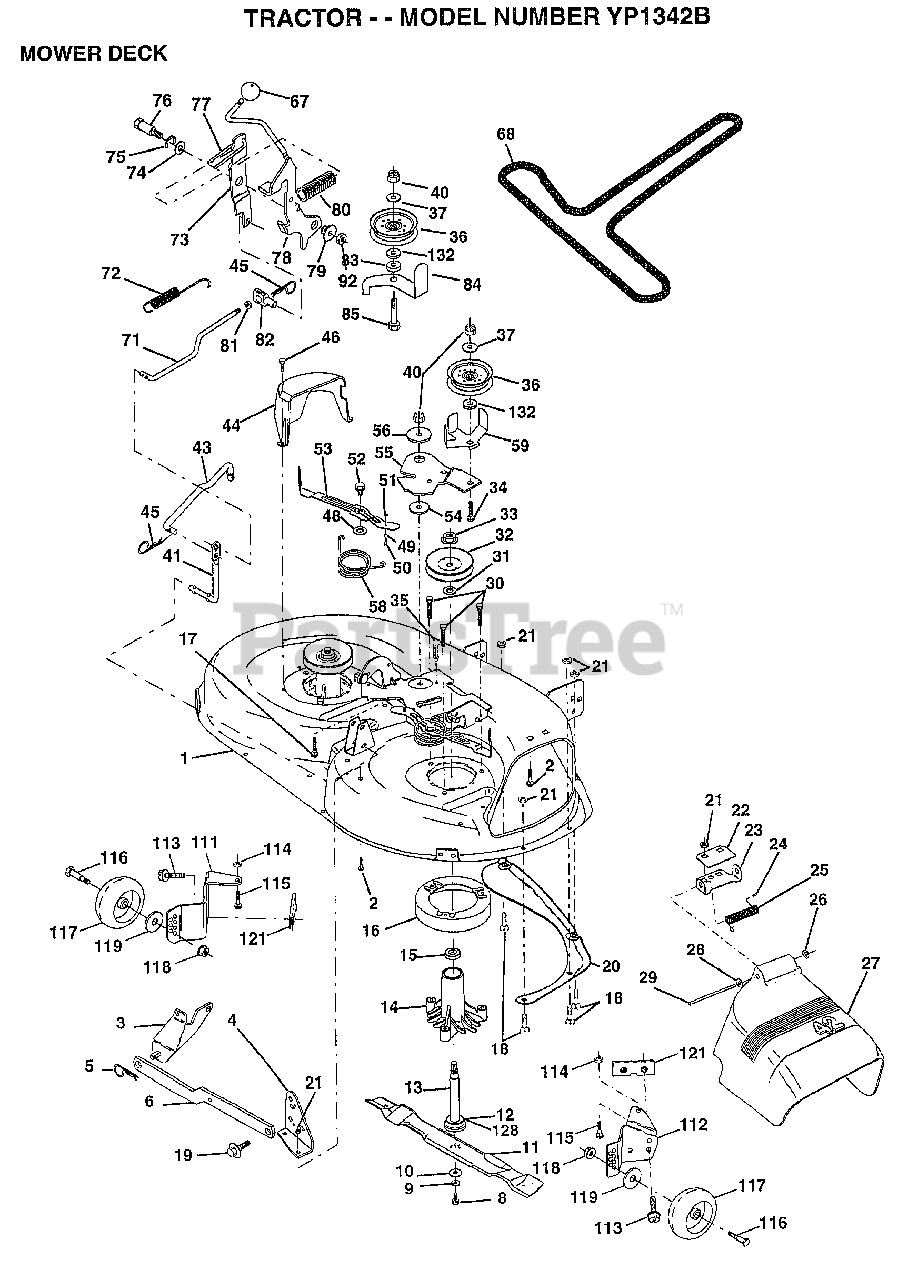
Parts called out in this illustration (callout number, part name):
1	DECK.WELD.42.
2	BOLT
3	BRKT ASM SWAY BAR
4	BRKT DECK SW BAR
8	BLADE BOLT
10	WASHER.HARD.BLADE
11	"BLADE.42"" HIPERF"
12	BEARING.BALL
14	HSG ASM MANDREL
15	BEARING
16	STRIPPER RND MWR
17	BOLT RDHD 3/8-16
18	BOLT
19	BOLT SHD 5/16-18
22	STIFFENER BRKT
23	DEFLECTOR BRKT
24	CAP-SLEEVE LT
25	SPRING TORSION
26	NUT PUSH M
27	DEFLECTOR.SHIELD
28	WASHER
29	HINGE ROD
30	"SCREW-THD ROLL,WA"
31	WASHER
32	PULLEY.MANDREL.42
34	BOLT
35	XMAS TREE FASTNER
36	FLAT IDLER PULLEY
37	WASHER
41	PIVOT ROD
43	ROD CLUTCH W/NIBS
44	GUARD MAND LH BLK
45	RETAINER M
46	SCREW.1/4-20X5/8
48	HARD SMALL WASHER
49	ROLLER ASM-CAM
50	SHOULDER BOLT
51	LOCKNUT
52	BOLT.SHLD.5/16-18
54	HARDENED WASHER
55	ARM-IDLER
56	SPACER RETAINER
58	SPRING TORSN BRAK
59	GUARD IDLER TUV
67	KNOB T(3/8 HOLE)
68	BELT.V.T-PATH
71	ROD CLUTCH 38/42
72	RETURN SPRING
73	CLUTCH ARM SECOND
74	WASHER
75	RING
76	SHOULDER BOLT
77	SPRING KEEPER
78	LEVER ASM-CLUTCH
79	BUSHING
80	SPRING.CLUTCH.MWR
81	TRUNION ADJ
82	NUT
83	WASHER
84	"KEEPER-BELT,FIXED"
85	BOLT RDHD 3/8-16
92	NUT
111	BRACKET.GWHL.LH.
112	BRACKET.GWHL.RH.
113	SCREW
116	BOLT.SHOULDER
117	WHEEL GAGE DONUT
118	LOCKNUT
119	WASHER
121	BRACKET.EXTRD.GWL
128	WASHER.FELT.
132	WASHER GT
